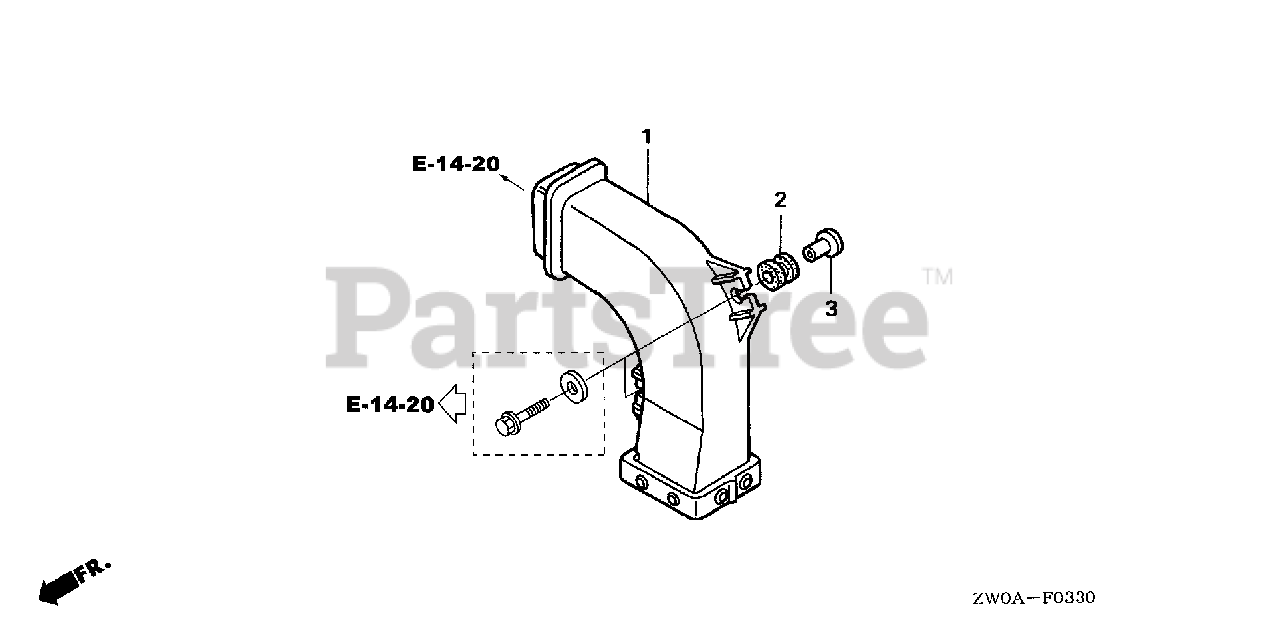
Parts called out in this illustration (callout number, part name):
1	DUCT, MUFFLER
2	GROMMET, CASE (LOWER)
3	COLLAR, MODULE IGNITION CONTROL CASE (CDI)
